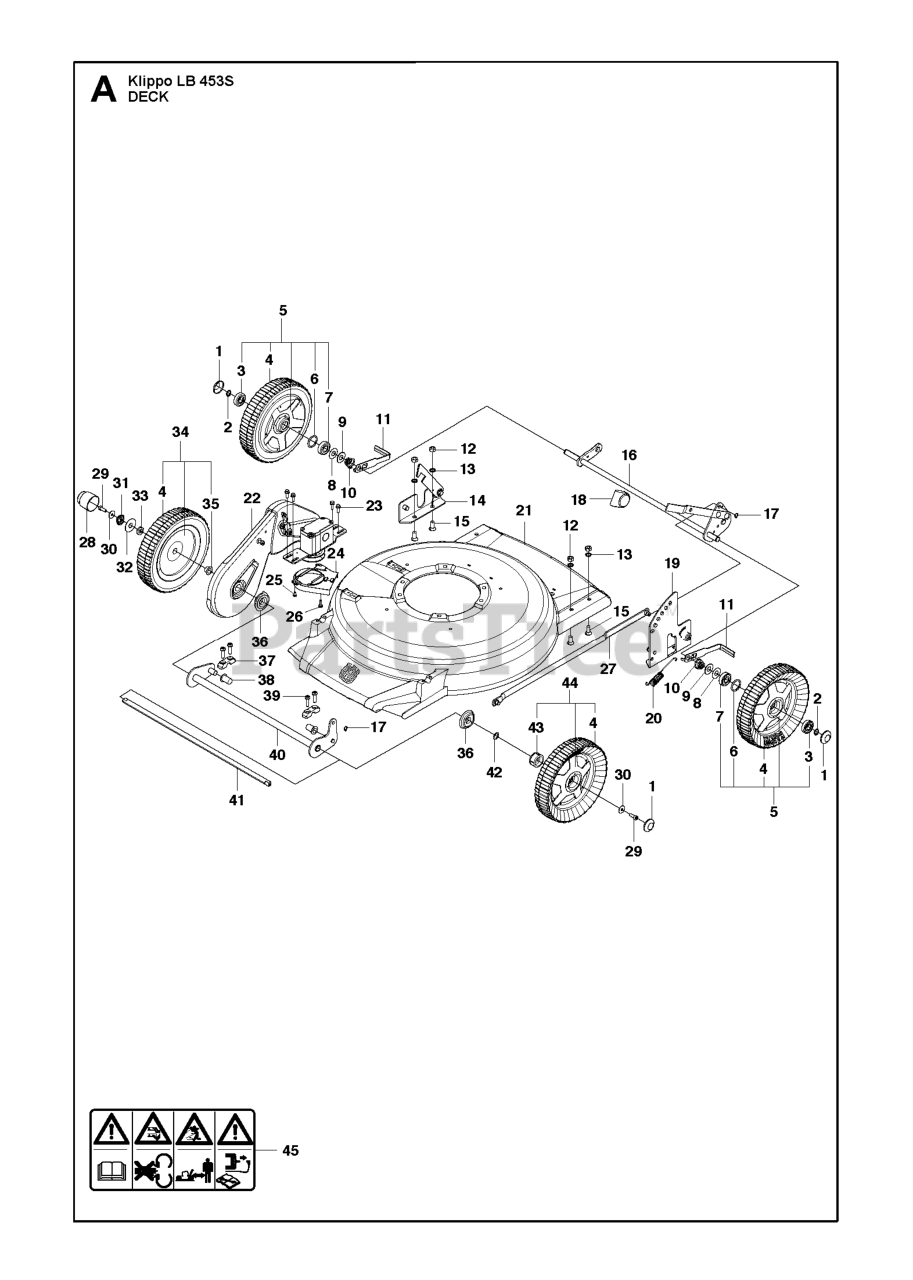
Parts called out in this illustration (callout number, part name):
1	STARTER ASSY
2	SPACING SLEEVE
3	STARTER ROPE
5	STARTER HANDLE
6	RP STARTER HOUSING
7	STARTER PULLEY ASSY.
8	SPACING SLEEVE
9	STARTER PAWL BRIDGE
12	STARTER PAWL
13	STARTER DECAL 326LS
15	SCREW
17	SCREW
